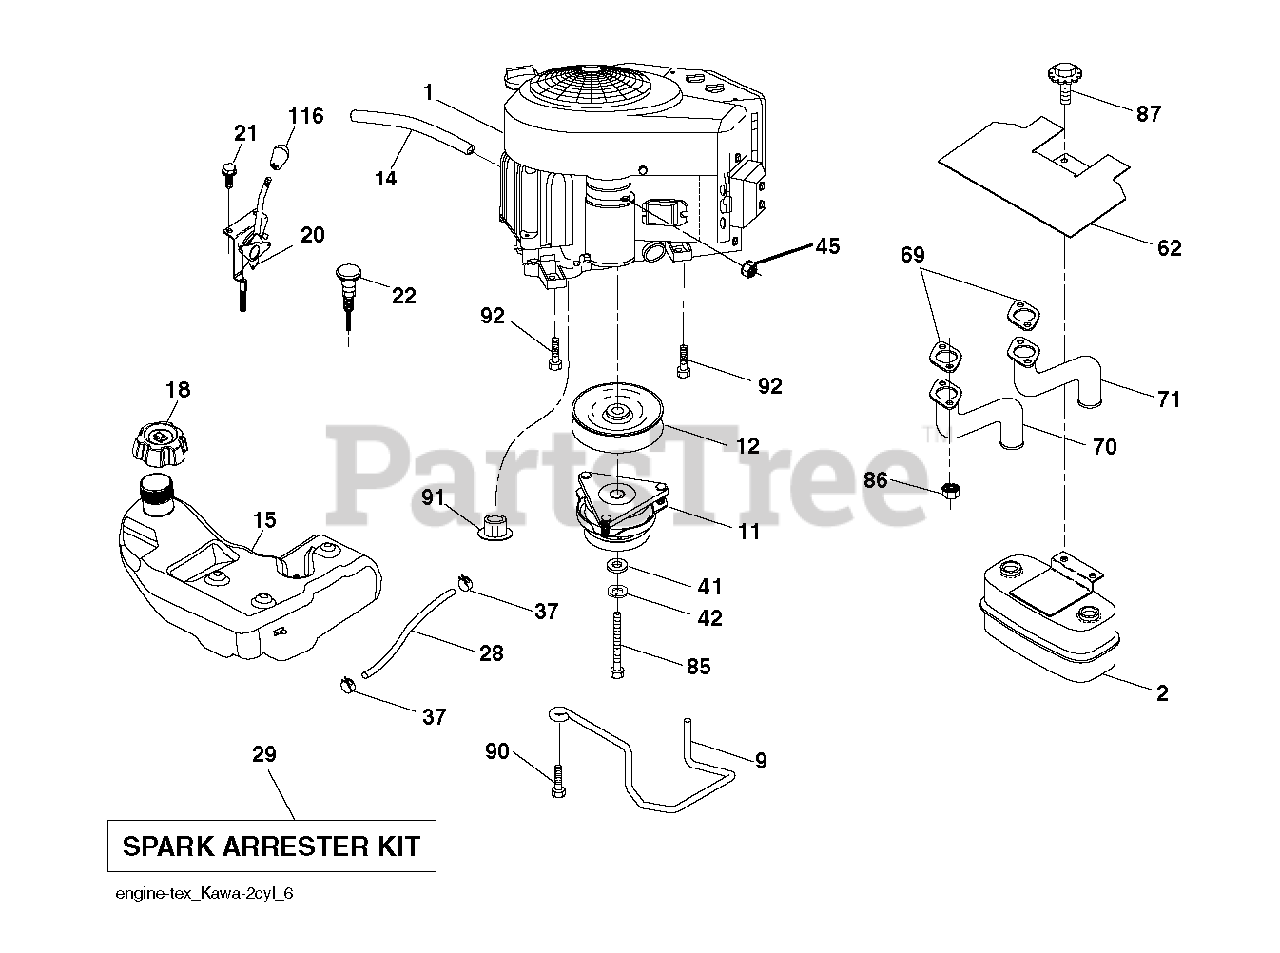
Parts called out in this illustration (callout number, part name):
1	Husqvarna TBD
2	MUFFLER.TWIN.CYL.LOW.TONE
9	KEEPER.BELT.ENGINE.4.2
11	CLUTCH.ELECTRIC.LT.48"*
12	PULLEY.ENGINE.TUFFTORQ
14	TUBE, DRAIN OIL ASM.
15	TANK.FUEL.SIDE-FILL.3.NON-EPA
18	RP CAP FUEL
20	CONTROL.THROTTLE.PRO.
21	SCREW.#10 X 0.750.BOS
22	CONTROL.CHOKE.ERGO.PUSH-IN.BLA
28	REPL BY 532 00 85-43
29	KIT.SPARK ARRESTOR 794945 B&S
37	HOSE CLAMP
42	LOCKWASHER
45	NUT
62	SHIELD.HEAT.MUFFLER
70	TUBE.EXHAUST.LH.FR961/FR730
71	TUBE.EXHAUST.RH.FR961/FR730
85	BOLT HEX 7/16-20X4-1/4"
86	NUT.HEX.FLANGE.TOPLOCK
87	Bolt, 5/16-18 X 1-3/4
90	SCREW 3/8-16X1
91	BUSHING.1.375OD
92	SCREW 3/8-16X1
116	KNOB - SHIFT
